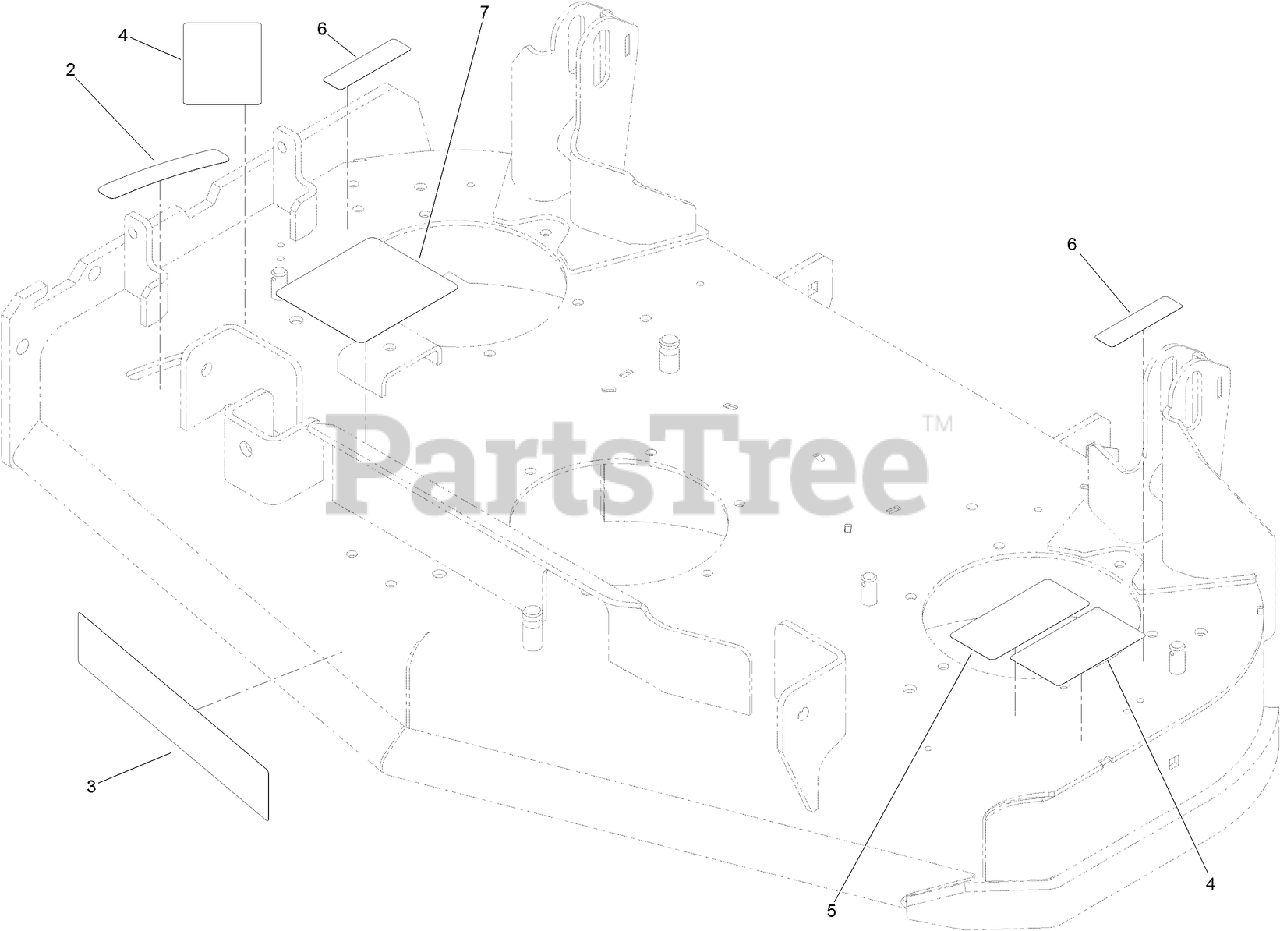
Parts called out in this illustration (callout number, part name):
2	DECAL-SETTING, BAFFLE
4	DECAL-DANGER
5	DECAL-TORQUE, BLADE BOLT
6	DECAL-DANGER
7	DECAL-ROUTING, BELT
